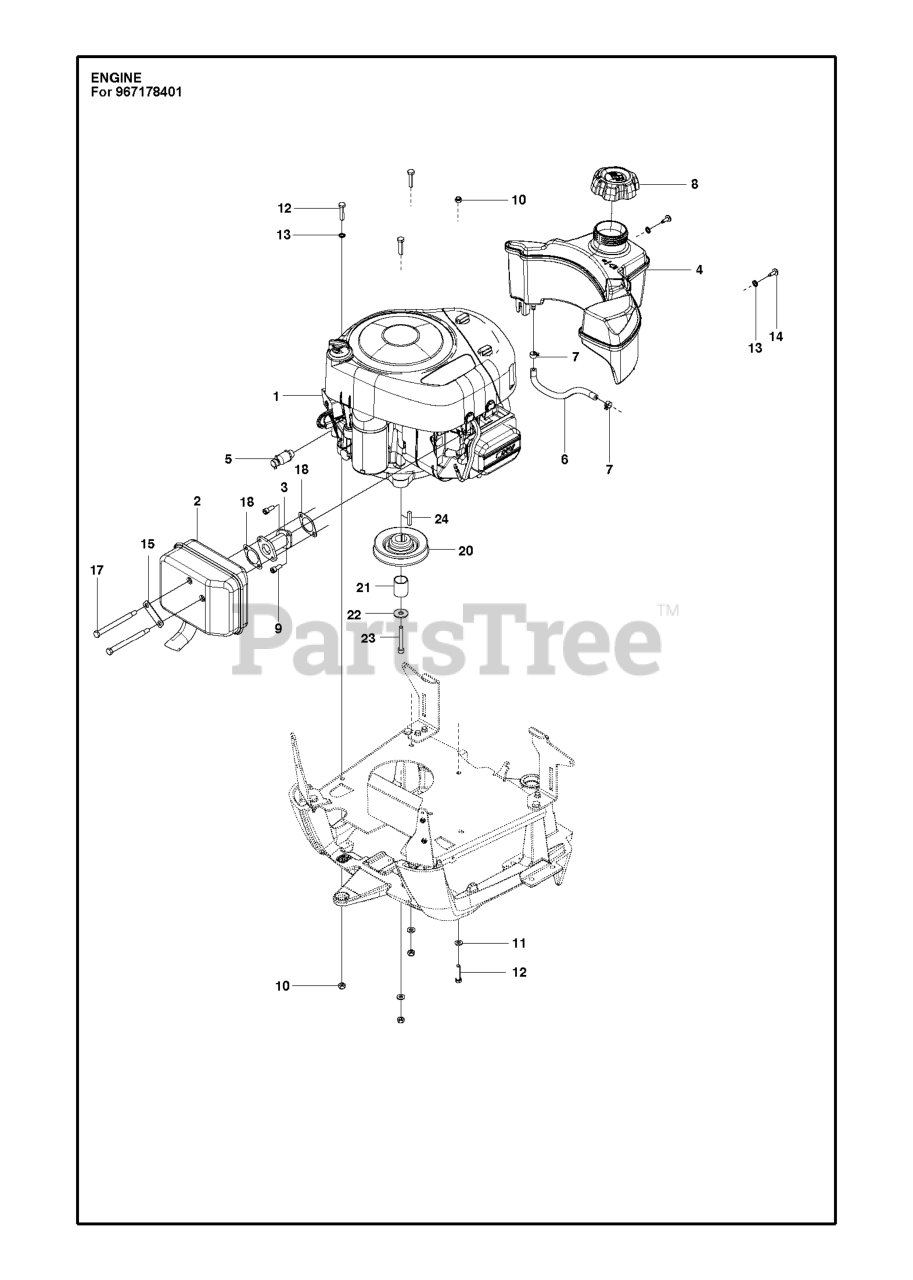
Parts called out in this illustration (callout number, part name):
8	CAP.FL.R.3'N/CARB.H.CROWN.498
10	LOCKNUT M8
11	WASHER BRB 8.4X17
